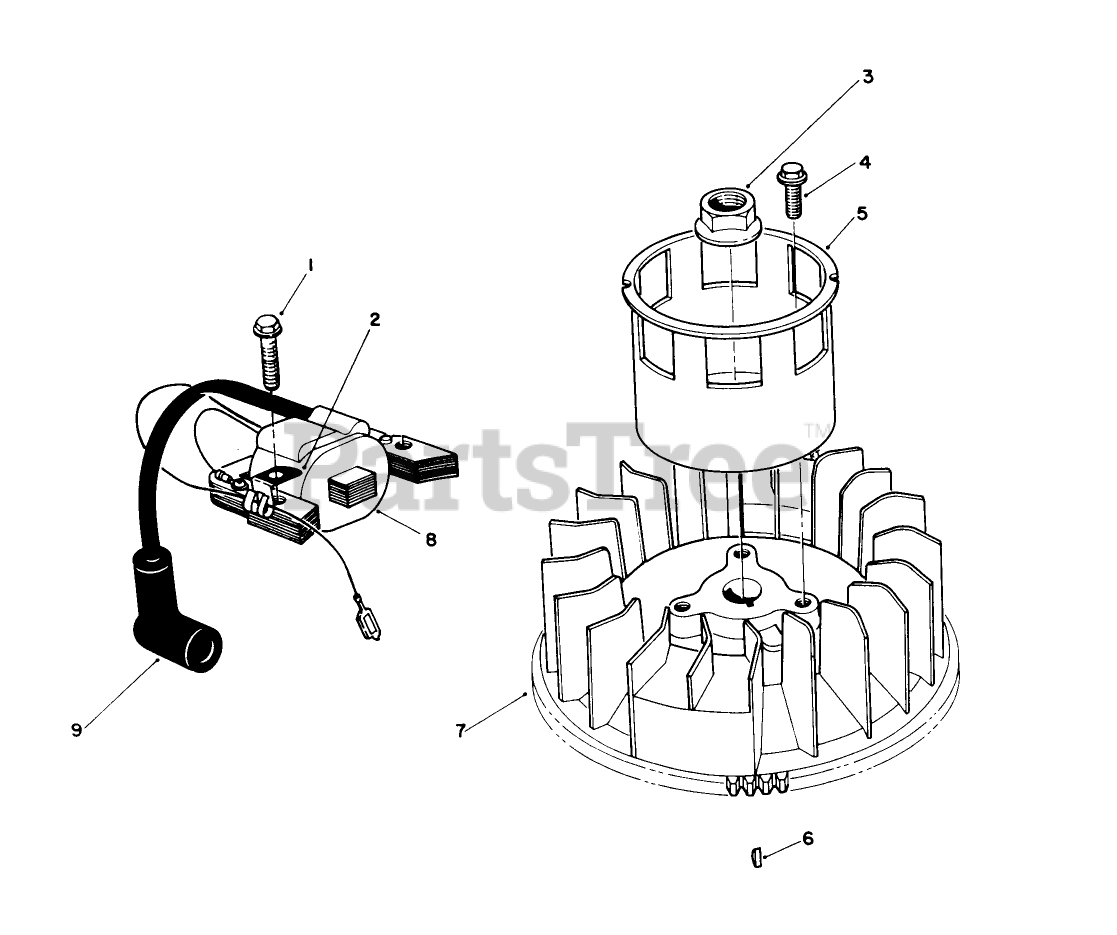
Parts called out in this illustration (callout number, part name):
2	CLAMP
7	FLYWHEEL
8	COIL ASM
9	COVER
